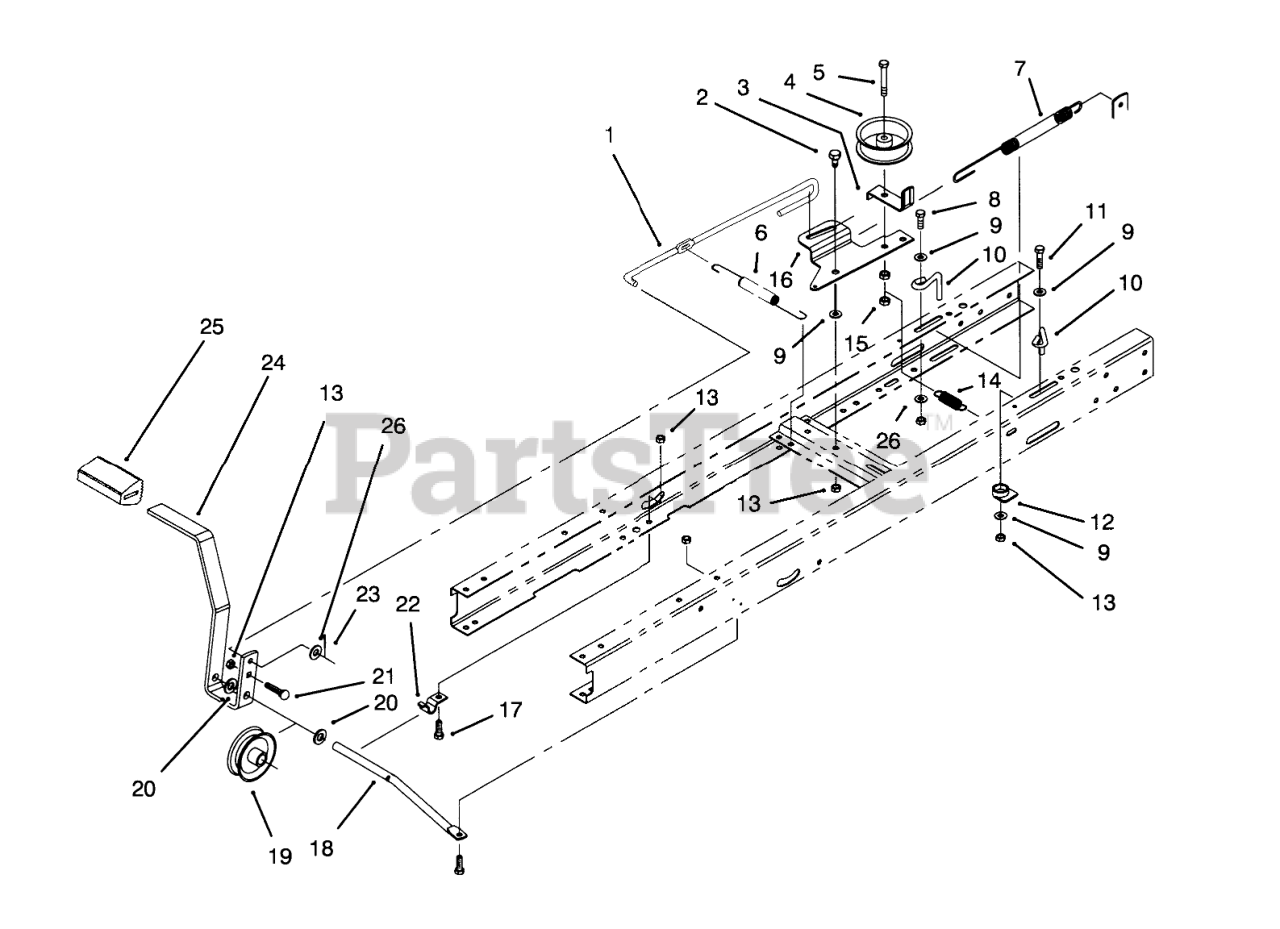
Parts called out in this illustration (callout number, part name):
1	ROD-CLUTCH/BRAKE
2	BOLT-SHOULDER
3	GUIDE-IDLER, BELT
4	Idler Pulley
5	SCREW-HH
6	SPRING-EXTENSION
7	BRAKE SPRING
8	SCREW-HH
9	WASHER-PIVOT
10	TRANS BELT GUIDE
11	SCREW-HH
12	GUIDE-CABLE
13	NUT-LOCK, NI
14	SPRING-EXTENSION
15	NUT-LOCK, NI
16	ARM-IDLER
17	SCREW-HH
18	ROD-PIVOT, PEDAL
19	PULLEY, CABLE
20	WASHER-FLAT
21	SCREW-CARR
22	CLAMP-PIVOT, SHIFT
23	PIN-COTTER
24	Pedal-Clutch/Brake
25	PAD-PEDAL
26	WASHER-PLAIN
